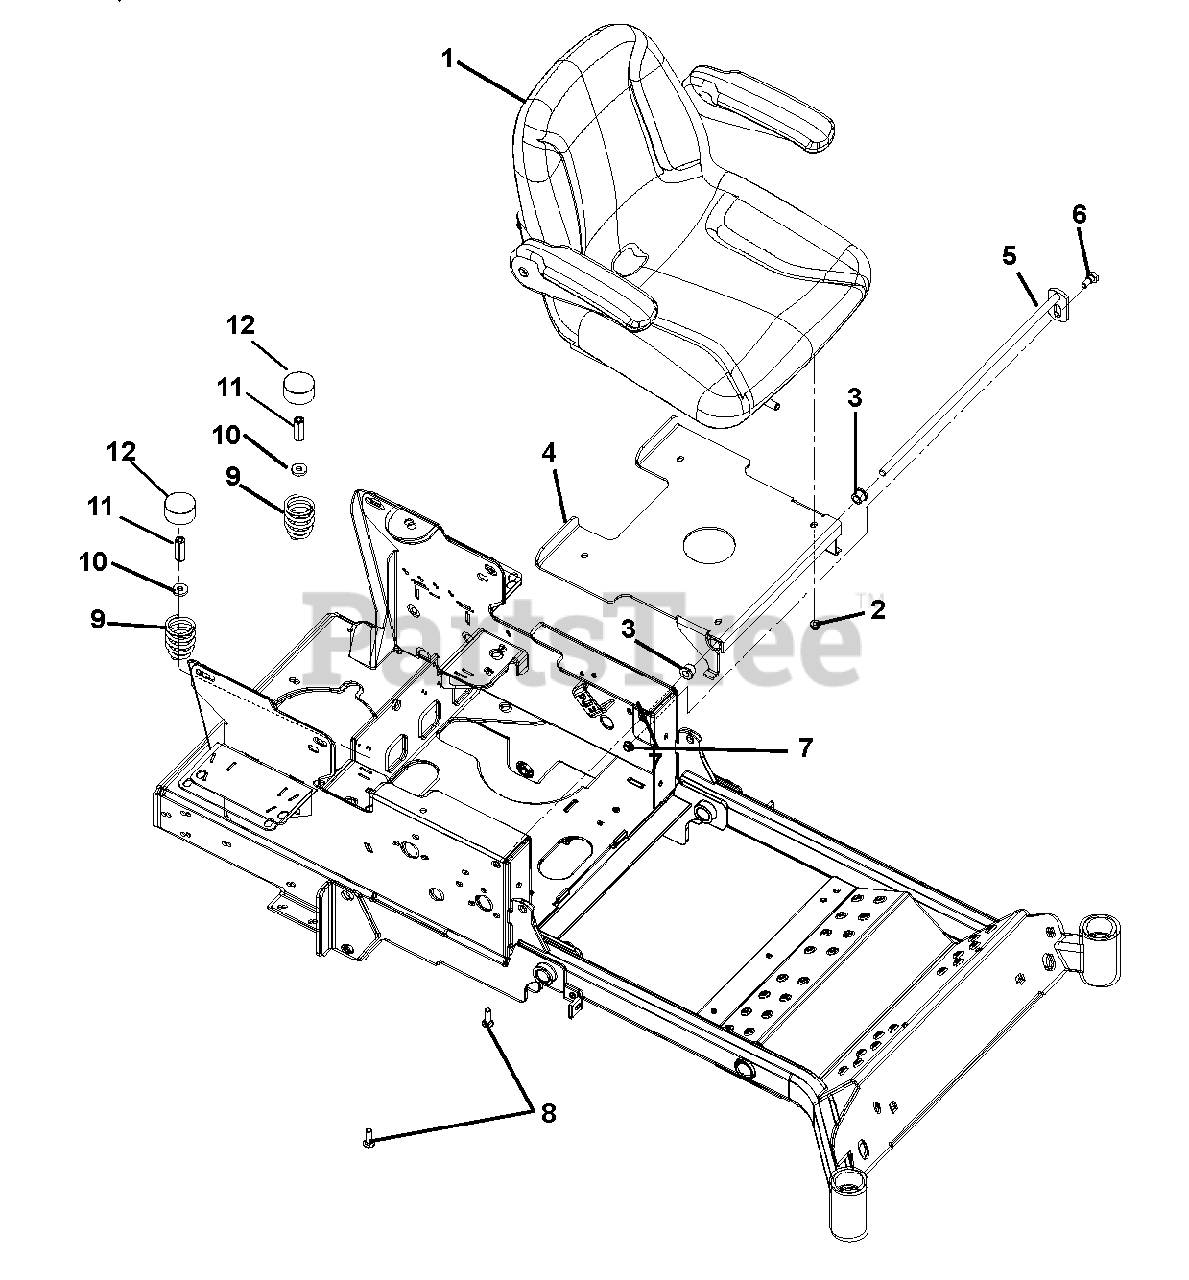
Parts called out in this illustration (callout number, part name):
1	ASSM, SEAT W/ ARMRESTS (GREY)
2	@NUT-LK-NYL-FLG .31-18 YWZC
3	BSHG, FLG .516X.750X.625X.937
4	WLDMT, SEAT PLATE
5	WMT, SEAT SHAFT
6	BLT,SHLDR EP .38-16X.30 HEX YZ
7	@NUT-LK-NYL-FLG .38-16 YWZC
8	@BLT-RDHDSQNK .38-16X1.25 G5YZ
9	SPRING, SEAT
10	WSHR-FL-STL .406X1.00X.188 YWZ
11	NUT COUPLING .375-16X1.75
12	HUB CAP
